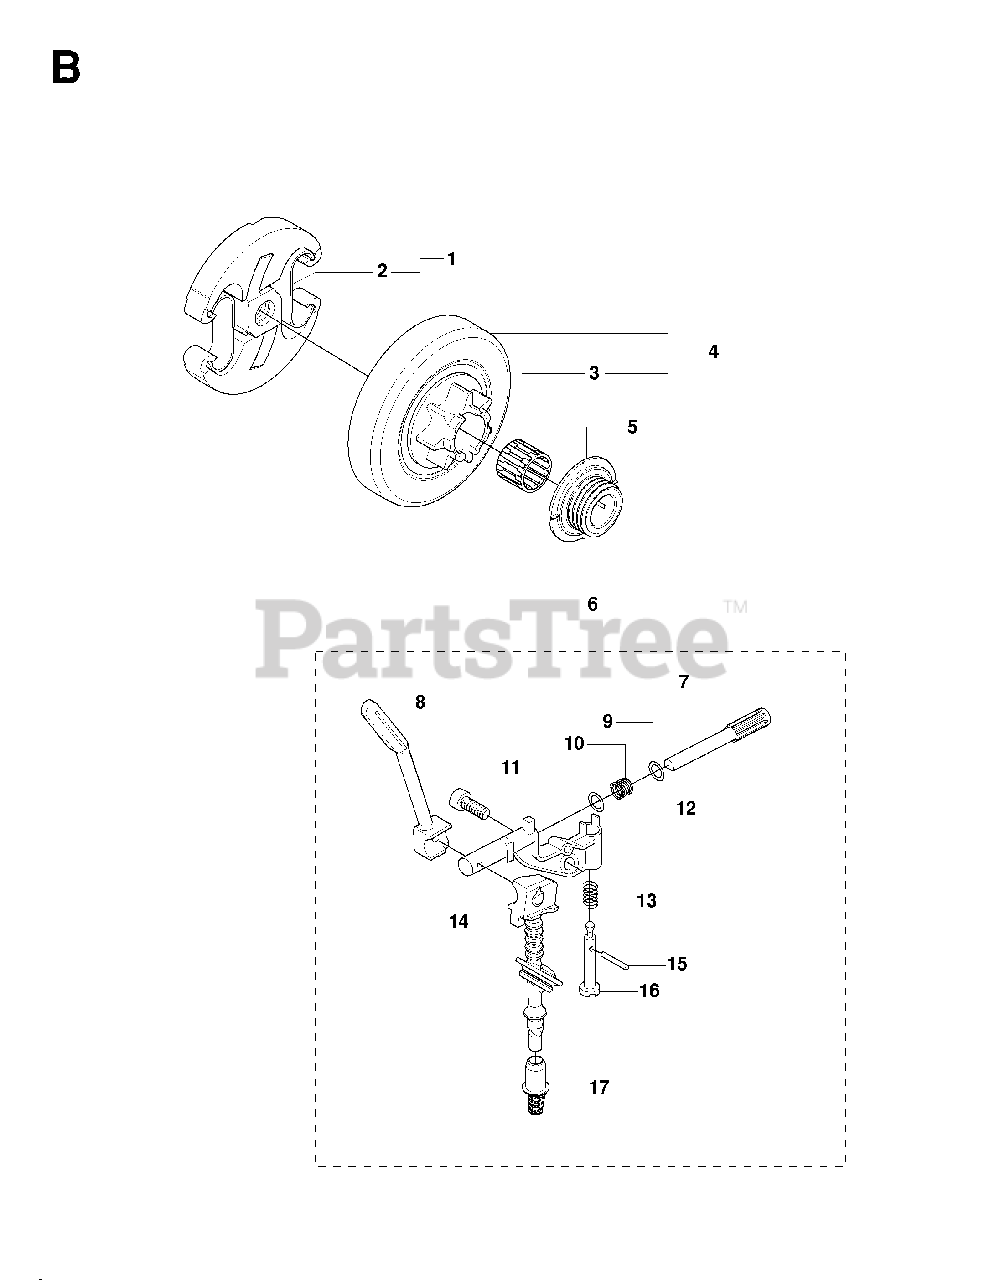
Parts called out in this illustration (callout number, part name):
3	NEEDLE BEARING
4	CLUTCH DRUM
5	PINION
6	OIL PUMP COMPLETE
7	%PUMP PISTON
14	RP OIL HOSE
17	%OIL SCREEN
